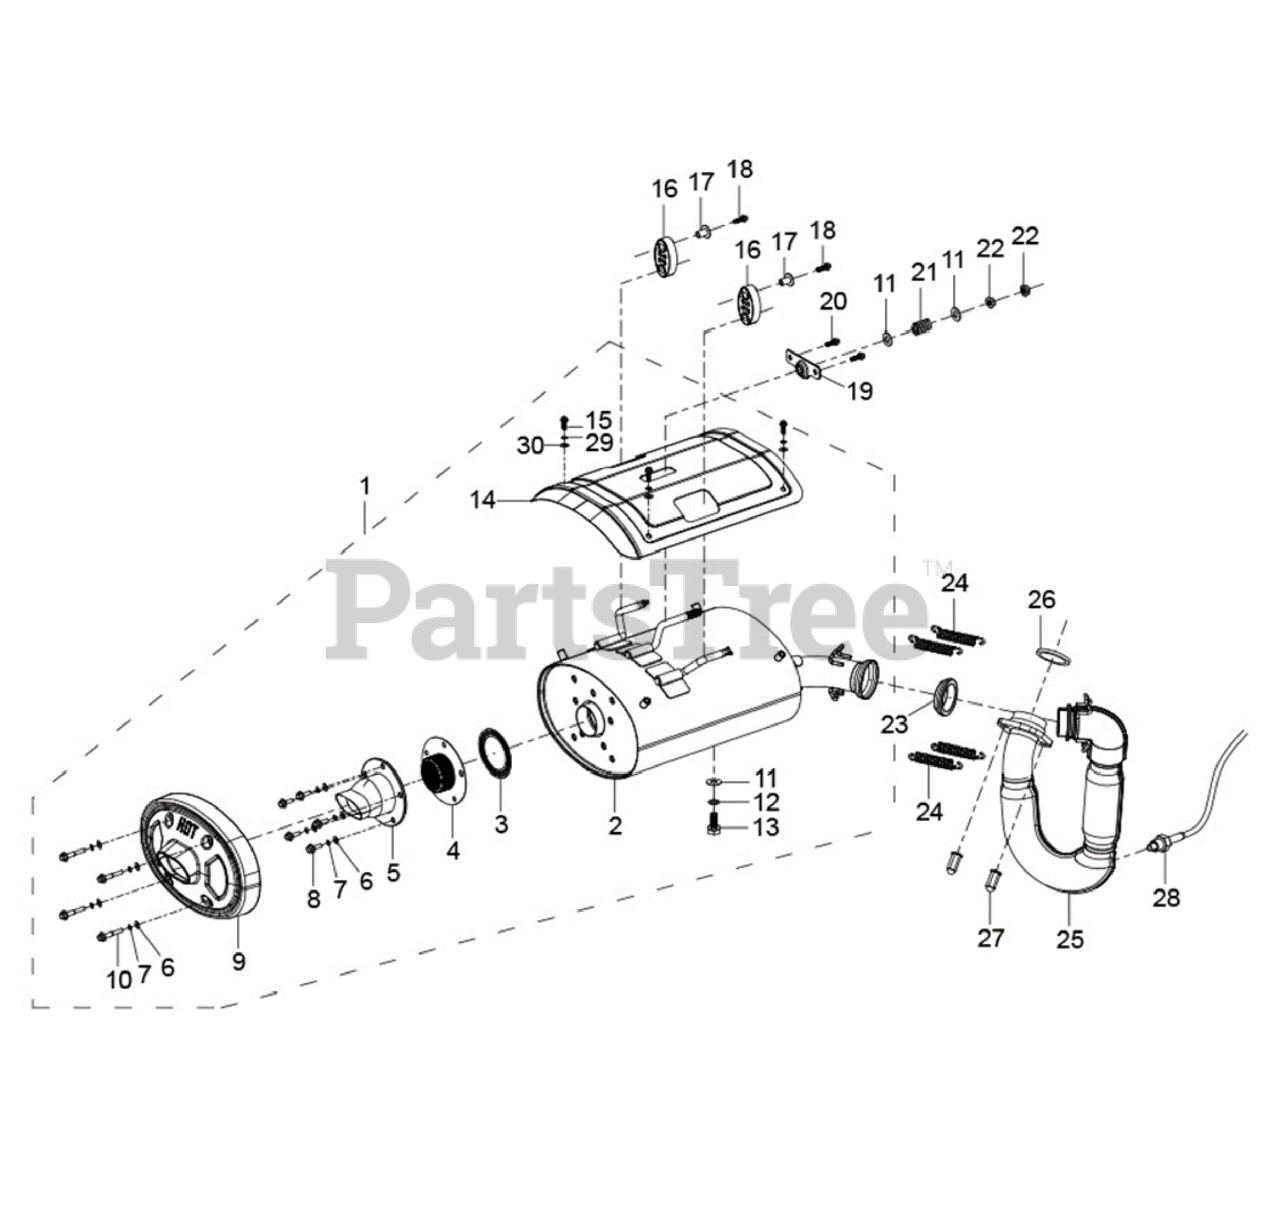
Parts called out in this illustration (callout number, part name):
1	MUFFLER ASSEMBLY
2	Muffler welding kit
3	HEAT PROTECTOR GASKET
4	SPARK ARRESTER
5	SPARK ARRESTOR COVER
6	WASHER - FLAT
7	WASHER - SPRING LOCK 8
8	Hexagon Flange BoltM6x20
9	MUFFLER CAP
10	BOLT HExAGON FLANGE HEAD M6x45
11	WASHER - FLAT 10x28x2
12	Spring Washer10
13	BOLT HExAGON FLANGE HEAD M10x1.25-20
14	MUFFLER HEAT PROTECTOR
15	BOLT HEx SOCKET M6x16
16	MUFFLER SHOCK PAD
18	Flange Bolt M6x25
19	MOUNTING PLATE
20	Hexagon Flange Bolt M6x16
21	PRESSURE SPRING P
22	HEXAGONAL NUT M10 X 1.25
23	DOMED WASHER
24	DRAW SPRING A
25	EXHAUST PIPE MANIFOLD
26	EXHAUST PIPE GASKET 36.5X46X6
28	OXYGEN SENSOR
29	WASHER - SPRING LOCK 8
30	WASHER - FLAT
